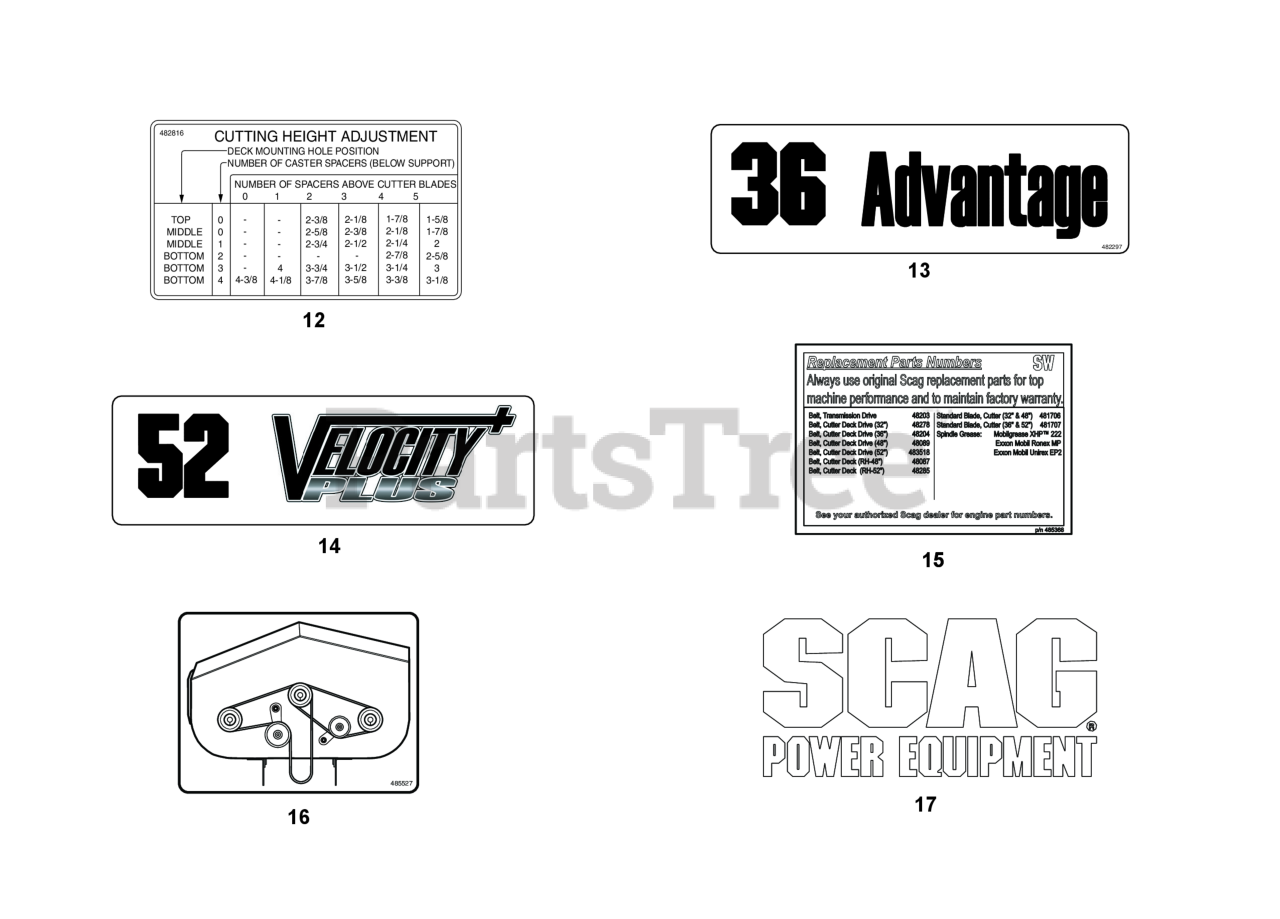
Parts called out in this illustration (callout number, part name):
12	DECAL, HEIGHT OF CUT - SWM
13	DECAL, ADVANTAGE - 36
15	Decal, SW Replacement Parts
16	Decal, Belt Routing - 32 & 36A
17	Decal, Scag Power Equipment (Fuel Tank)
